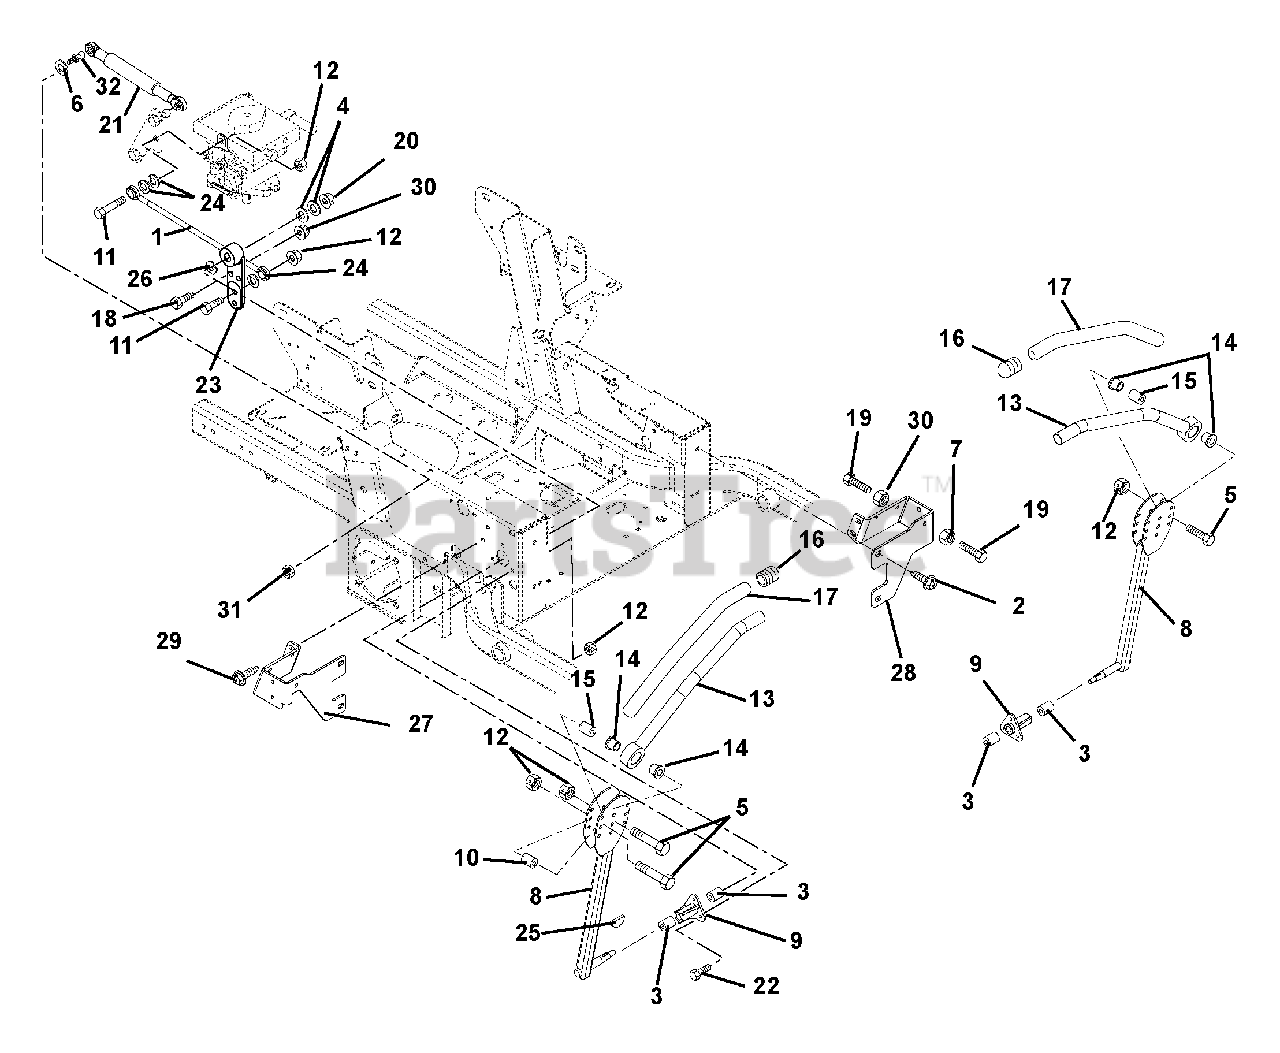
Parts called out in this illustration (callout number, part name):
1	Assembly, Steering Rod
2	Screw, Tapping .38-16 x .75 Hex Washer Head
3	Bushing .625 x .75 x .50
4	Washer, Flat Steel .38 x .875 x .083
5	Bolt, Hex .31-18 x 1.75 Grade 5
6	Washer, Flat Steel .344 x .688 x .065
7	Nut, Hex Jam .375-16
8	Control Arm
9	Housing, Bushing
10	Eccentric
11	Bolt, Hex .31-18 x 1.25 Grade 5
12	Nut, Locking Top Flange .31-18
13	Handle, Left Hand
13	Handle, Right Hand
14	Bushing, Flange Nylon .762 x 1.48 x .44
16	Caplug, Handlebar
17	Grip, Handlebar
18	Bolt, Hex .375-16 x 1.75
19	Bolt, Hex .38-16 x 1.25 Grade 5
20	Nut, Locking Top Flange .38-16
21	Damper, Control
22	Bolt, Hex .31-18 x .75 Grade 5
23	Arm, Pivot
24	Washer, Locking .31 x .078 Regular
25	Key, Woodruff .13 x .63
26	Wave Washer
27	Stop, Steering - Right Hand
28	Stop, Steering - Left Hand
29	Screw, Tapping .38-16 x .50 Hex Washer Head
30	Nut, Locking Jam Center .375-16
31	Nut, Locking Nylon M8-1.25
32	Stud, Ball
